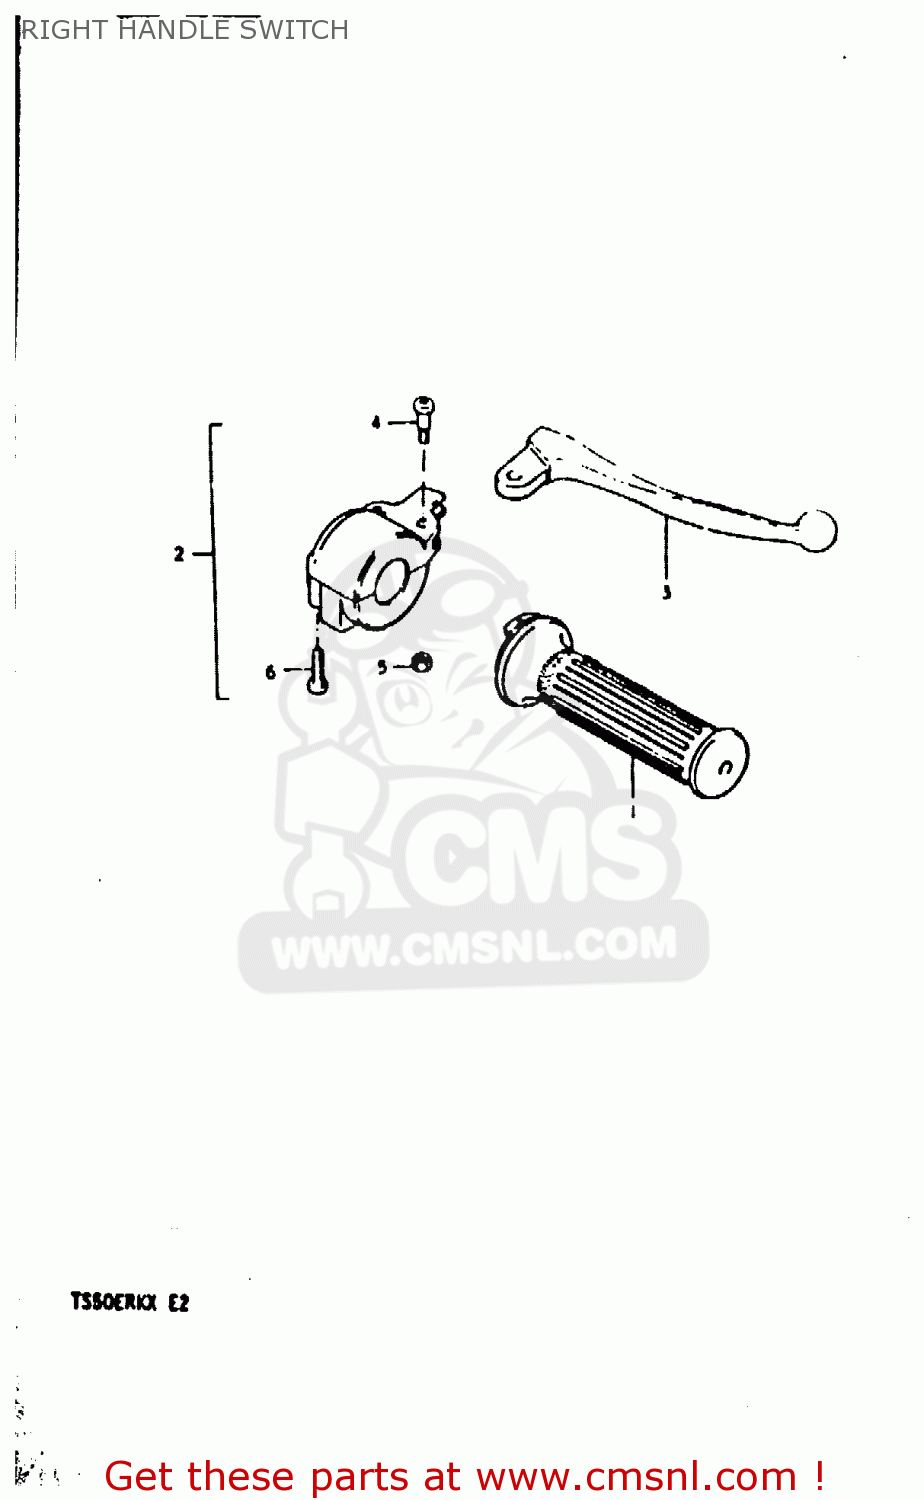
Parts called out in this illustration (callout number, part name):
1	GRIP,THROTTLE
2	BRAKE LEVER & SWITCH ASSY
3	LEVER
4	BOLT,LEVER
5	NUT,LEVER BOLT
6	SCREW
